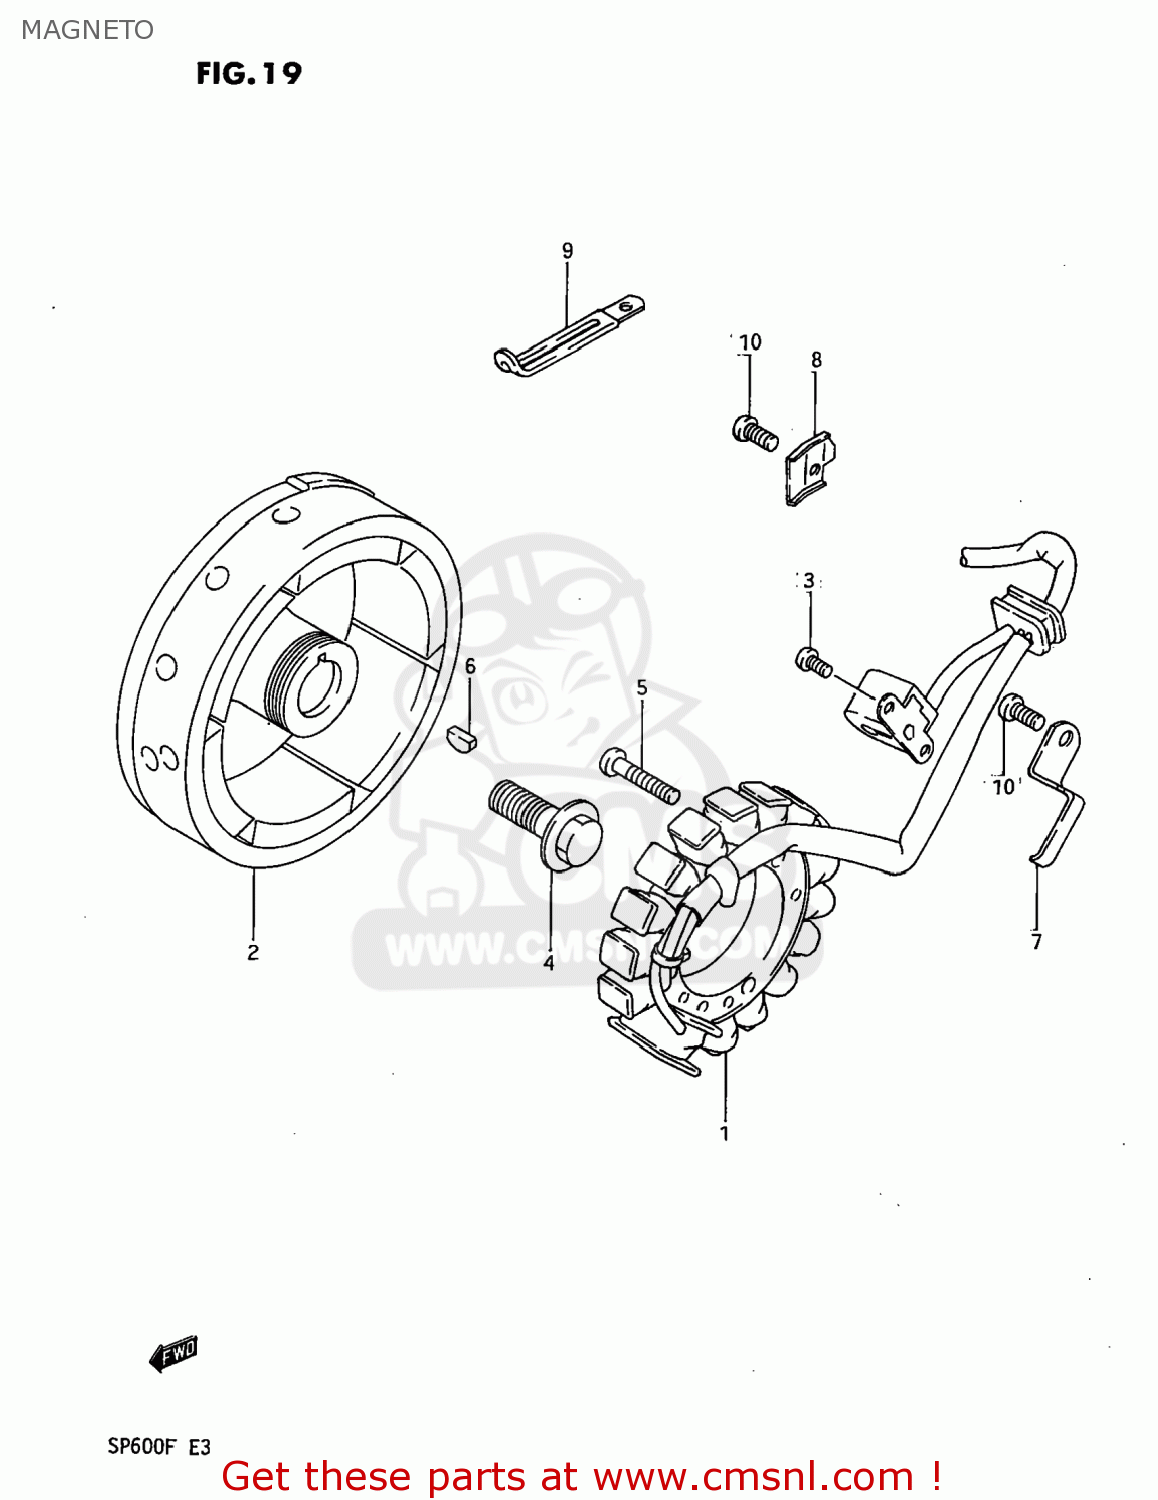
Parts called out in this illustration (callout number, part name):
1	STARTER ASSY
2	ROTOR ASSEMBLY
3	SCREW 5X12
4	BOLT(14X43)
5	SCREW,6X30
6	KEY 4MM
7	CLAMP,MAGNETO LEAD WIRE
8	CLAMP,MAGNETO LEAD WIRE
9	CLAMP
10	SCREW
